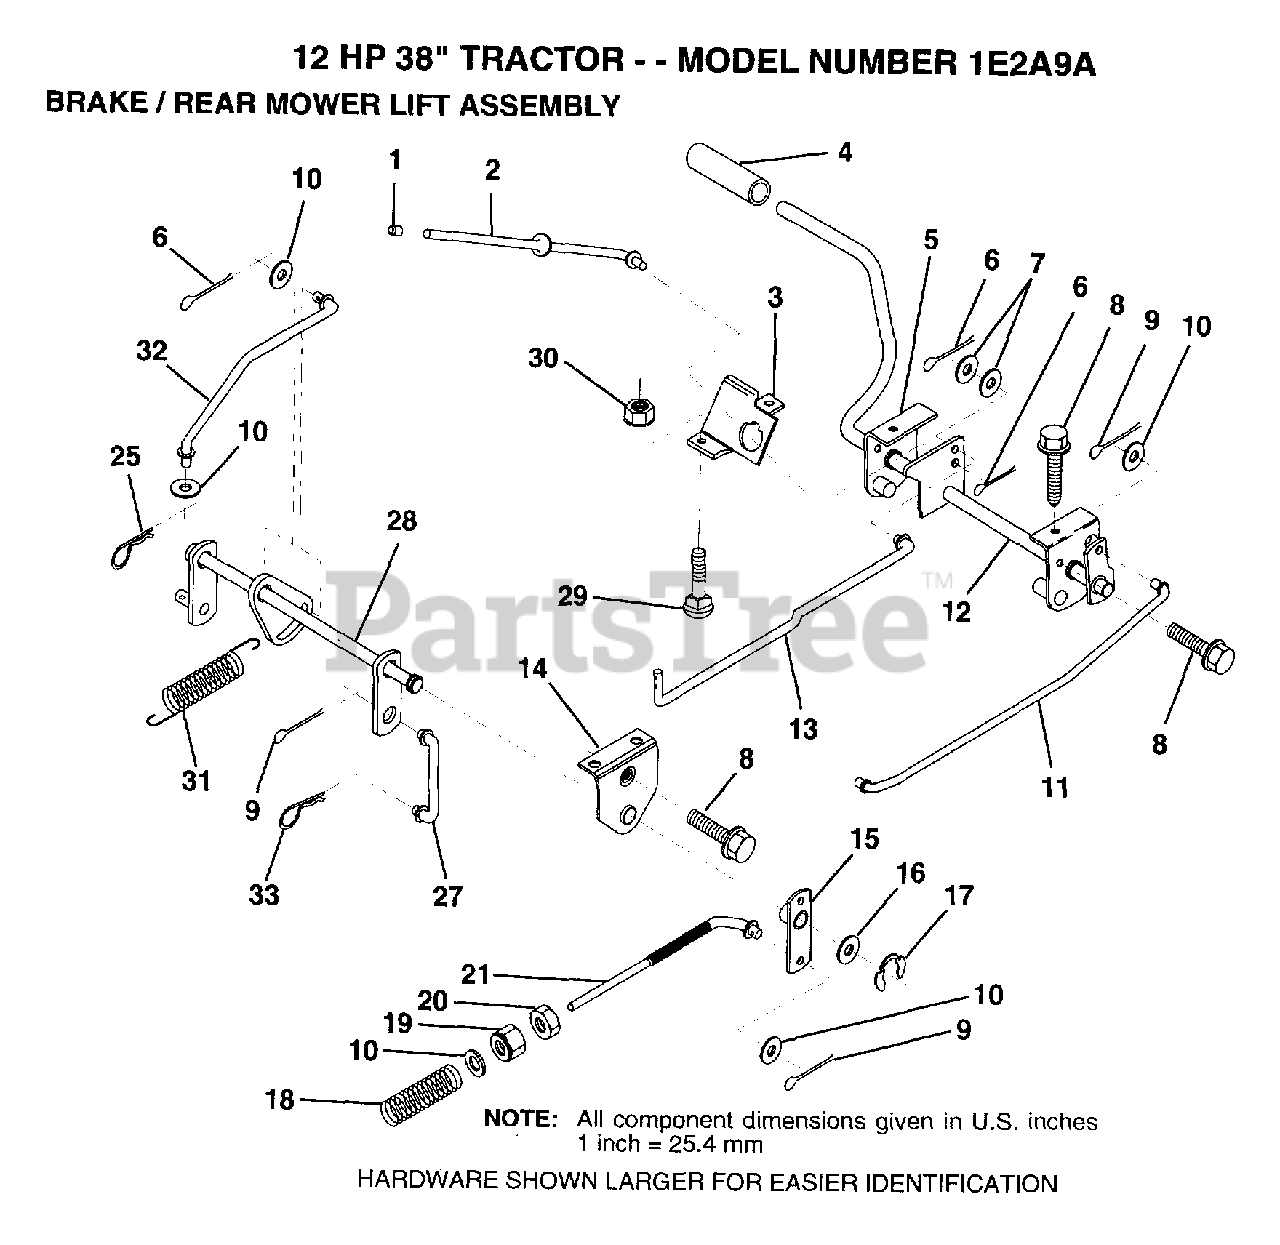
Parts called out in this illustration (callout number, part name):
1	PLUNGER CAP T
2	"ROD,PARK BRAKE"
3	"BRKT,PARK BRAKE"
4	PEDAL COVER T
5	BRK ASM CLUT LH
7	WASHER
8	SCREW LT
9	COTTER PIN
10	WASHER
11	"ROD,FRT BRAKE"
12	ASM CLUTCH/BRK PD
13	"ROD,CLUTCH"
14	"BRKT,LIFT SHAFT"
15	BRAKE PIVOT ARM
16	WASHER T
17	KLIP RING
18	SPRING ROD LT
19	NUT
25	SPRING.RETAINER
27	LINK LIFT REAR LR
28	LIFT ASM MWR RE
31	COUNTER SPRING
32	LINK LIFT LEVER
